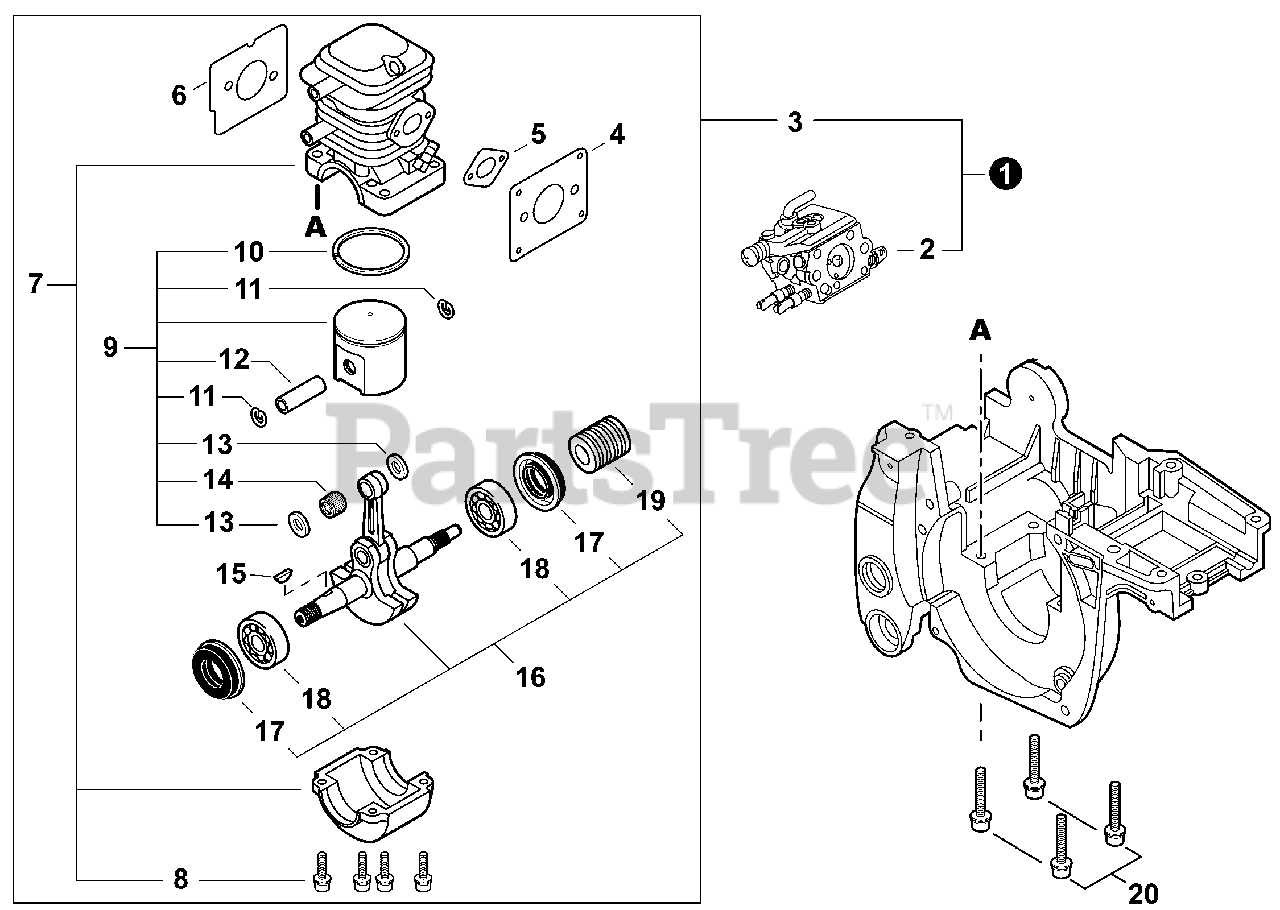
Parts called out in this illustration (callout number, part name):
1	SHORT BLOCK AND CARBURETOR WT-981
2	CARBURETOR WT-981
3	SHORT BLOCK
4	GASKET, INTAKE
5	GASKET, INTAKE
6	GASKET, EXHAUST
7	CRANKCASE SET
8	BOLT 5×22
9	PISTON KIT
10	RING, PISTON
11	RING, SNAP
12	PIN, PISTON
13	WASHER, THRUST
14	BEARING, NEEDLE 9
15	KEY, WOODRUFF
16	CRANKSHAFT ASSY
17	SEAL, OIL 12
18	BEARING, BALL 6201
19	GEAR, WORM
20	BOLT 5×30
